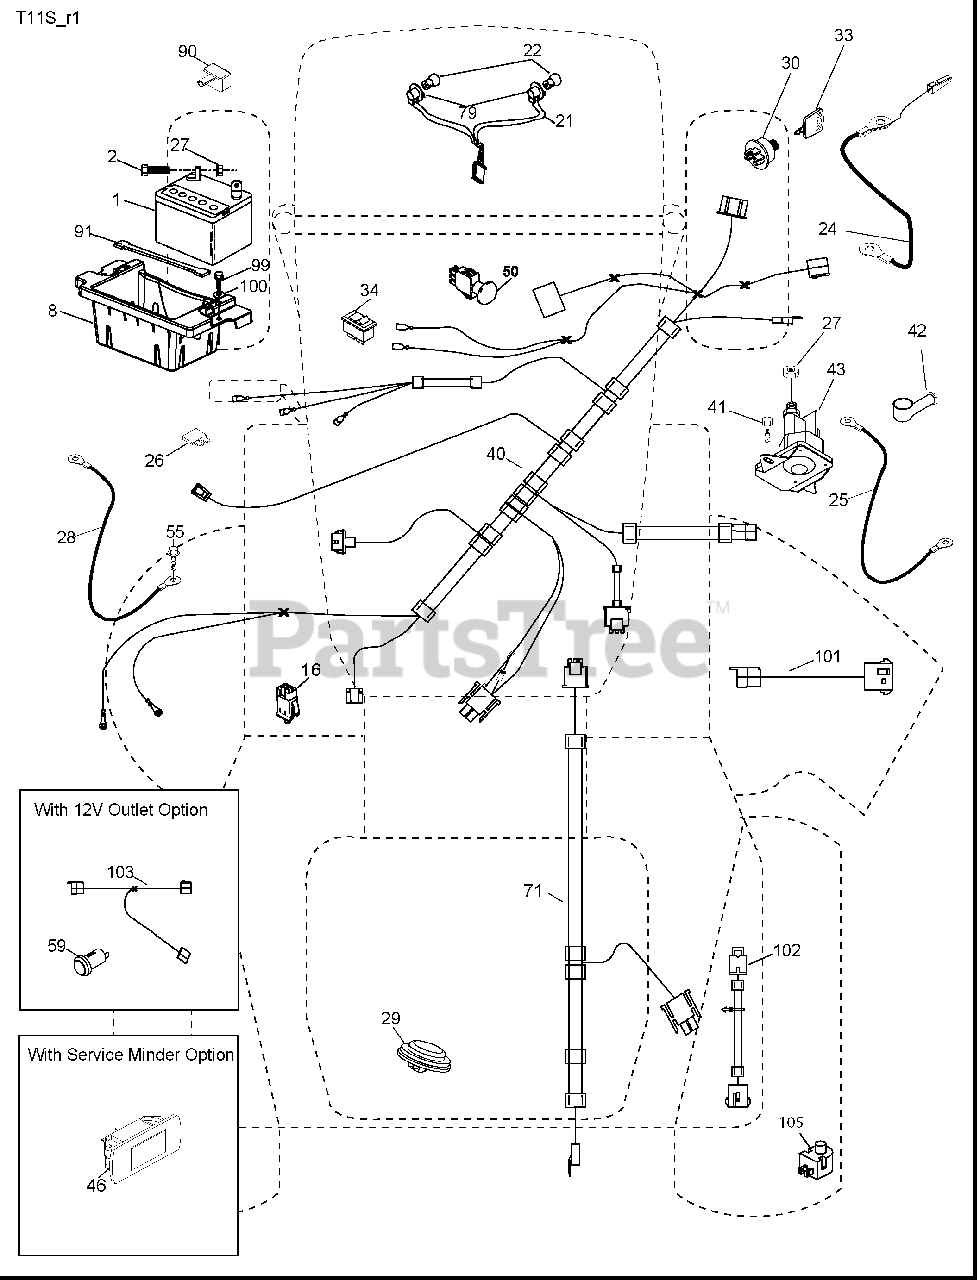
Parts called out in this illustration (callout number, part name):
1	Battery
2	Bolt Hex Head 1/4-20 x 3/4
8	Box Battery
16	Switch Interlock Push-In
21	Harness Socket Light w/4152J
22	Bulb Light
24	Cable Battery
25	Cable Starter
26	Fuse
27	Nut Keps. Hex 1/4-20 unc
28	Cable, Ground
29	Switch, Seat
30	Switch, Ign.
33	Key/Chain
34	Switch Light/Reset
40	Harness Ign. Dash
41	Screw Thd. Cut 1/4-20 x 1/2
42	Cover, Terminal
43	Solenoid
46	Gauge Hourmeter
50	Switch PTO
55	Screw Thdrol. 5/16-18 x 3/4 TYTT
71	Harness Chassis
79	Socket Asm. Bulb Twistlock
90	Cover Terminal Battery
91	Strap Battery Mount Front
99	Screw Hex Wsh. Thdrol. 1/4-20 x 3/4
100	Washer 9/32 x 7/8 x 16 Ga.
101	Pigtail
102	Harness Pigtail K46 TEX ROS
105	Switch Reverse TT Pedal Control
